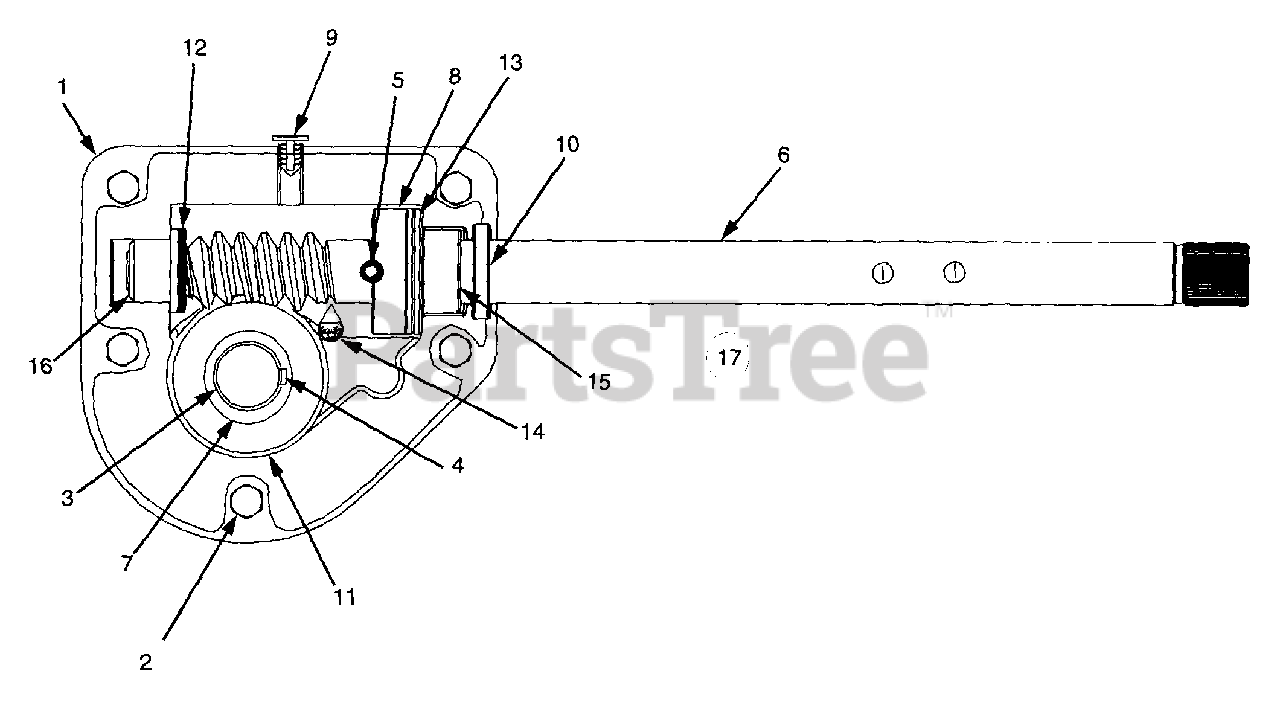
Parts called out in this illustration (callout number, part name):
1	Housing - L.H.
2	Hex Screw 1/4-20 x .75
3	Spiral Axle 22"
4	Key
5	Pin-Spiral
6	Shaft-Worm
7	Gear-Worm
8	Collar-Thrust
10	Seal-Oil
11	Washer-Flat
12	Washer-Flat
13	Washer-Flat
14	Grease
15	Bearing-Flange
16	Bearing-Flange
17	Ass'y. Complete 22"
